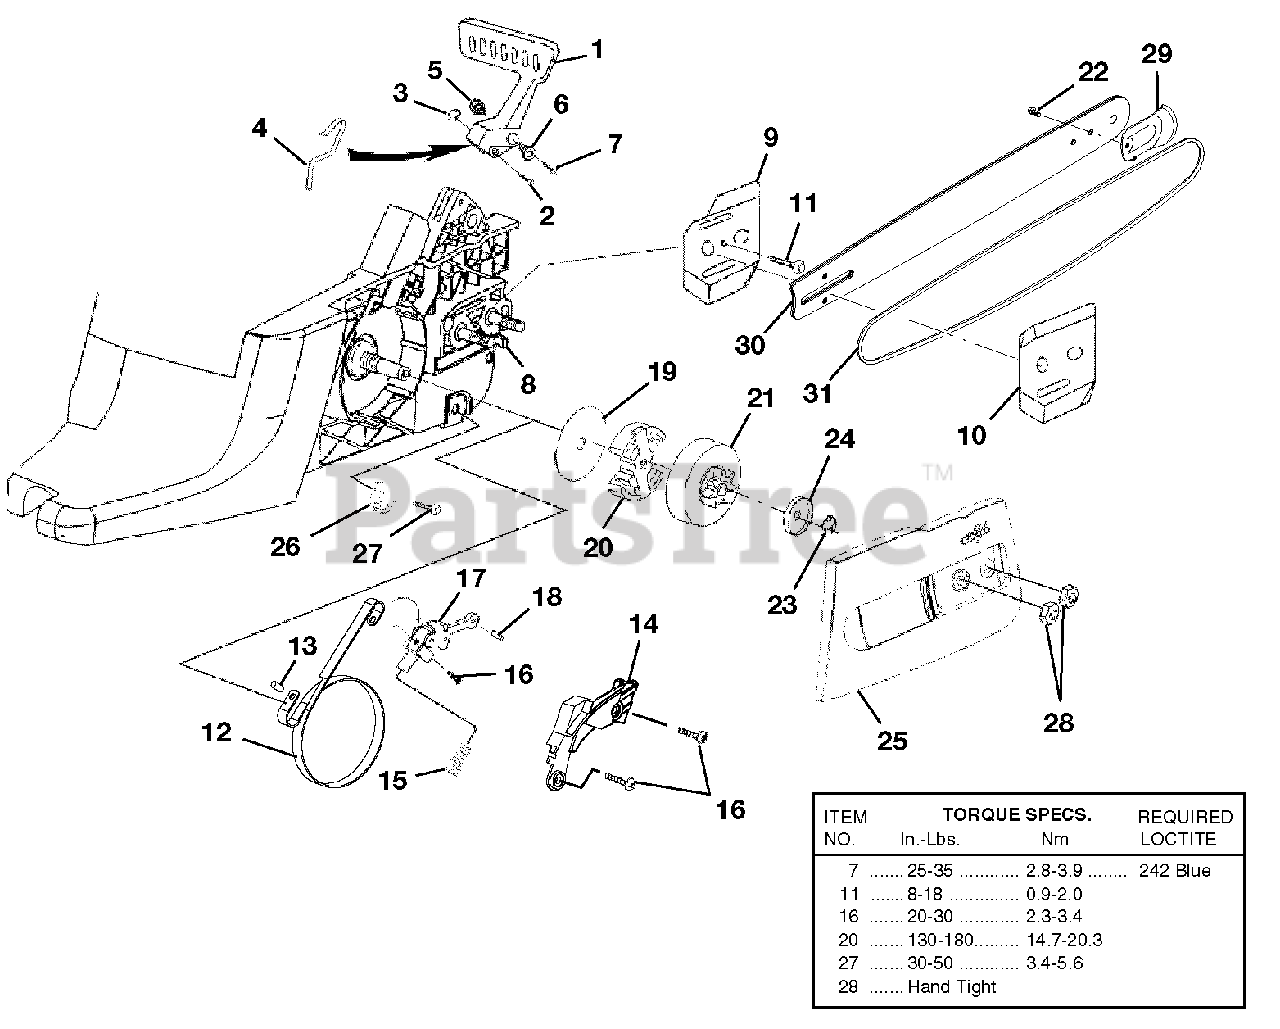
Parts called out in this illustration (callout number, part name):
1	Hand Guard
2	Hand Guard Actuating Pin
3	Retaining Ring
4	Hand Guard Spring
5	Pivot, L.H.
6	Pivot, R.H.
7	Screw (8-32 x 5/8 in.)
8	Adjust Screw Assembly
9	Guide Bar Plate
10	Guide Bar Plate
11	Screw (6-19 x 1/2 in.)
12	Brake Band
14	Chain Brake Cover
15	Compression Spring
16	Screw (8-16x5/16 in.)
17	Chain Brake Link Assembly
19	Thrust Washer
20	Clutch & Handware
21	Drum Sprocket and Bearing Assembly (.375 Pitch)
22	Screw-Safety Tip (Hex Hd.)
23	Retaining Ring
24	Cupped Washer
25	Drive Case Cover Assembly
26	Chain Catcher
27	Screw (10-24x 1/2 in.)
29	Safety Tip
30	Guide Bar
